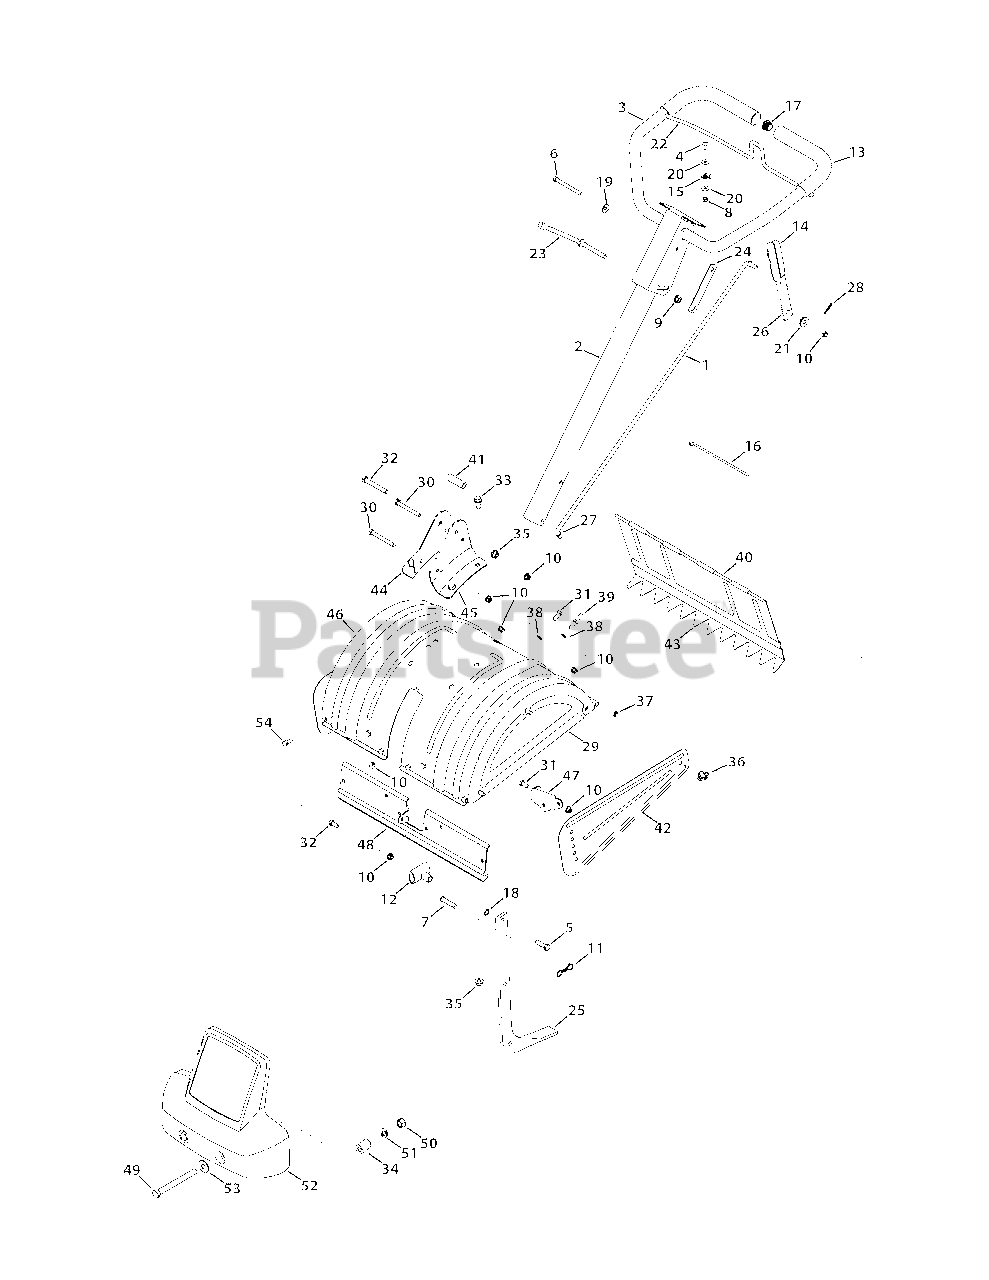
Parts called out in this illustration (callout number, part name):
1	Shift Rod
2	Lower Handle Tube Assembly
3	Upper Handle Assembly
4	Screw, 1/4-20 x 0.625
5	Hex Screw, 3/8-16:1.25
6	Hex Screw, 5/16-18 x 3.25
7	Clevis Pin, .375 X 1.75
8	Hex Lock Nut, 1/4-20
9	Flange Lock Nut, 3/8-24
10	Hex Lock Nut, 5/16-18
11	Cotter Pin
12	Small Tee Knob
13	Foam Grip, .970 x 11.0
14	Grip, .1875 x 1.00
15	Battery Clamp, 5/16
16	Cable Tie, 11.15
17	End Plug
18	Flat Washer, .385 x .620 x .033
19	Bell Washer, .340 x .872 x .060
20	Flat Washer, .260 x .720 x .060
21	Spacer, .50 x .190 x .360
22	Clutch Bail
23	Handle Adjustment Crank
24	Hex Nut Retainer Bracket
25	Tiller Depth Control
26	Shaft Rod Lever
27	Washer, .33 x .87 x .125
28	Cotter Pin, .072 x 1.12
29	End Cover Assembly
30	Hex Screw, 5/16-18 x 2.75
31	Hex Screw, 5/16-18 x 1.00
32	Hex Screw, 3/8-16 x 2.75
33	Hex Flange, 3/8-16 x .875
34	Hub, .636 x 1.00 x .94
35	Flange Lock Nut, 3/8-16
36	Wing Nut, 5/16-18
37	Speed Nut Cap, 1/4
38	Flat Washer, .344 x .62 x .033
39	Screw, Hex, 5/16-18 x .75
40	Tiller Flap Rod
41	Spacer, .322 x .625 x 2.00
42	Side Shield
43	Rear Tine Shield
44	RH Handle Mount Bracket
45	LH Handle Mount Bracket
46	Tine Shield
47	FRT Tine Shield Bracket
48	FRT Tine Shield Spacer Bracket
49	Hex Screw, 1/2-20 x 5.50
50	Hex Lock Nut, 1/2-20
51	Flat Washer, 1/2 x 1.25 x .10
52	Counterweight
